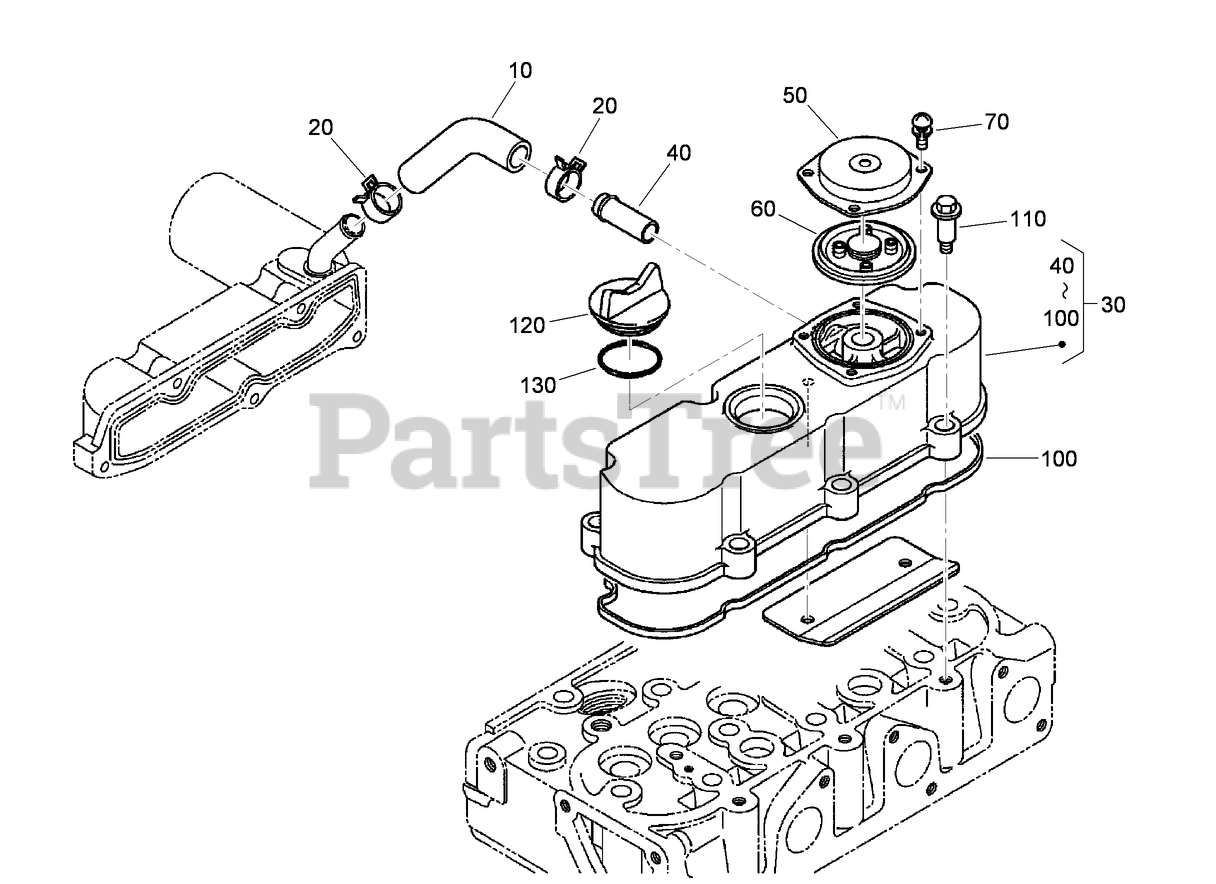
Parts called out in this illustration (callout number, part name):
10	TUBE-BREATHER
20	CLAMP-HOSE
30	CYLINDER HEAD COVER ASM
40	PIPE-RETURN, WATER
50	COVER-BREATHER
60	VALVE-BREATHER
70	SCREW (WITH WASHER)
100	GASKET-COVER, HEAD
120	PLUG-FILLER, OIL
130	O-RING
